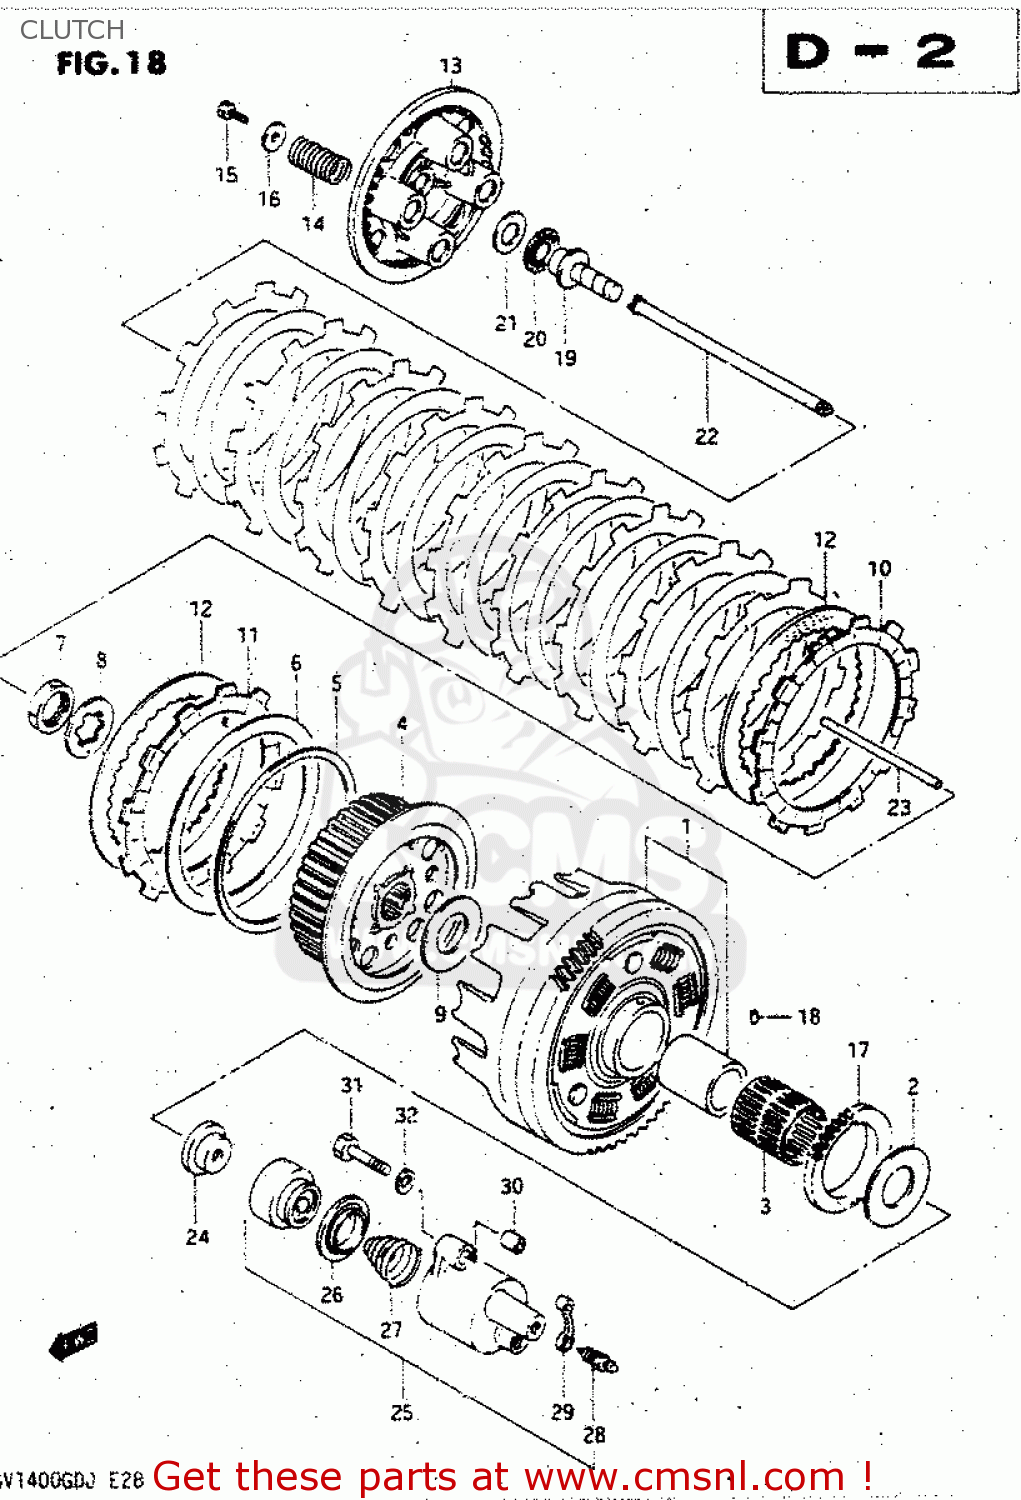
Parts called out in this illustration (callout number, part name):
1	GEAR ASSEMBLY,PRIMARY DRIVE
2	WASHER
3	BEARING(35X40X39.8)
4	HUB COMP,CLUTCH SLEEVE
5	SEAT,WAVE WASHER(T:1.4)
6	WASHER
7	NUT
8	WASHER,LOCK
9	WASHER(25X50X2.5)
10	PLATE,CLUTCH DRIVE
11	PLATE,CLUTCH DRIVE(T:3.5) (NAS)
12	PLATE,CLUTCH DRIVEN(T:1.6) (NAS)
13	DISC,CLUTCH PRESSURE
14	SPRING
15	BOLT
16	WASHER
17	GEAR,OIL PUMP DRIVE
18	PIN(6X6)
19	PIECE,CLUTCH PUSH
20	BEARING
21	WASHER
22	ROD,CLUTCH PUSH
23	ROD,CLUTCH PUSH,L
24	SEAL,OIL(6X36X6)
25	CYLINDER,CLUTCH RELEASE
26	CUP,CLUTCH CYLINDER
27	SPRING,CLUTCH CYLINDER
28	BLEEDER
29	CAP,BLEEDER
30	PIN
31	BOLT ,6X35
32	WASHER,LOCK
